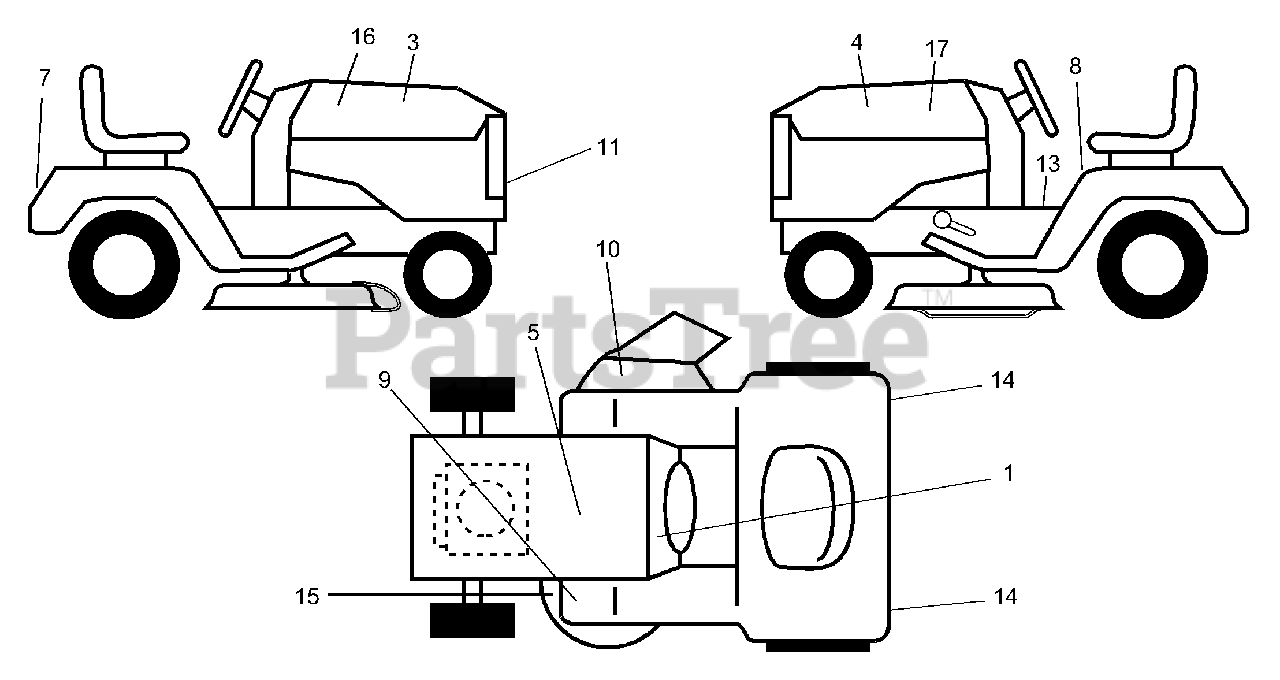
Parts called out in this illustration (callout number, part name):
1	Decal Instruction Dash Eng/fr
3	Decal Hood RH Husq
4	Decal Hood LH Husq
5	Decal Bat Dan/Poi P/L Symbols
7	Decal Fender Husqvarna
8	Decal Caution Fender Eng/fr
9	Decal Clutch/brake Eng/fr
10	Decal Warning MULT-LANGUAGE
11	Decal Grille Husqvarna
13	Decal Brake Parking Saddle
14	Reflector Tail Light Red/amber
15	Decal V-Belt Mower Multi-Lang.
16	Decal Insert Hood Rh
17	Decal Insert Hood Lh
